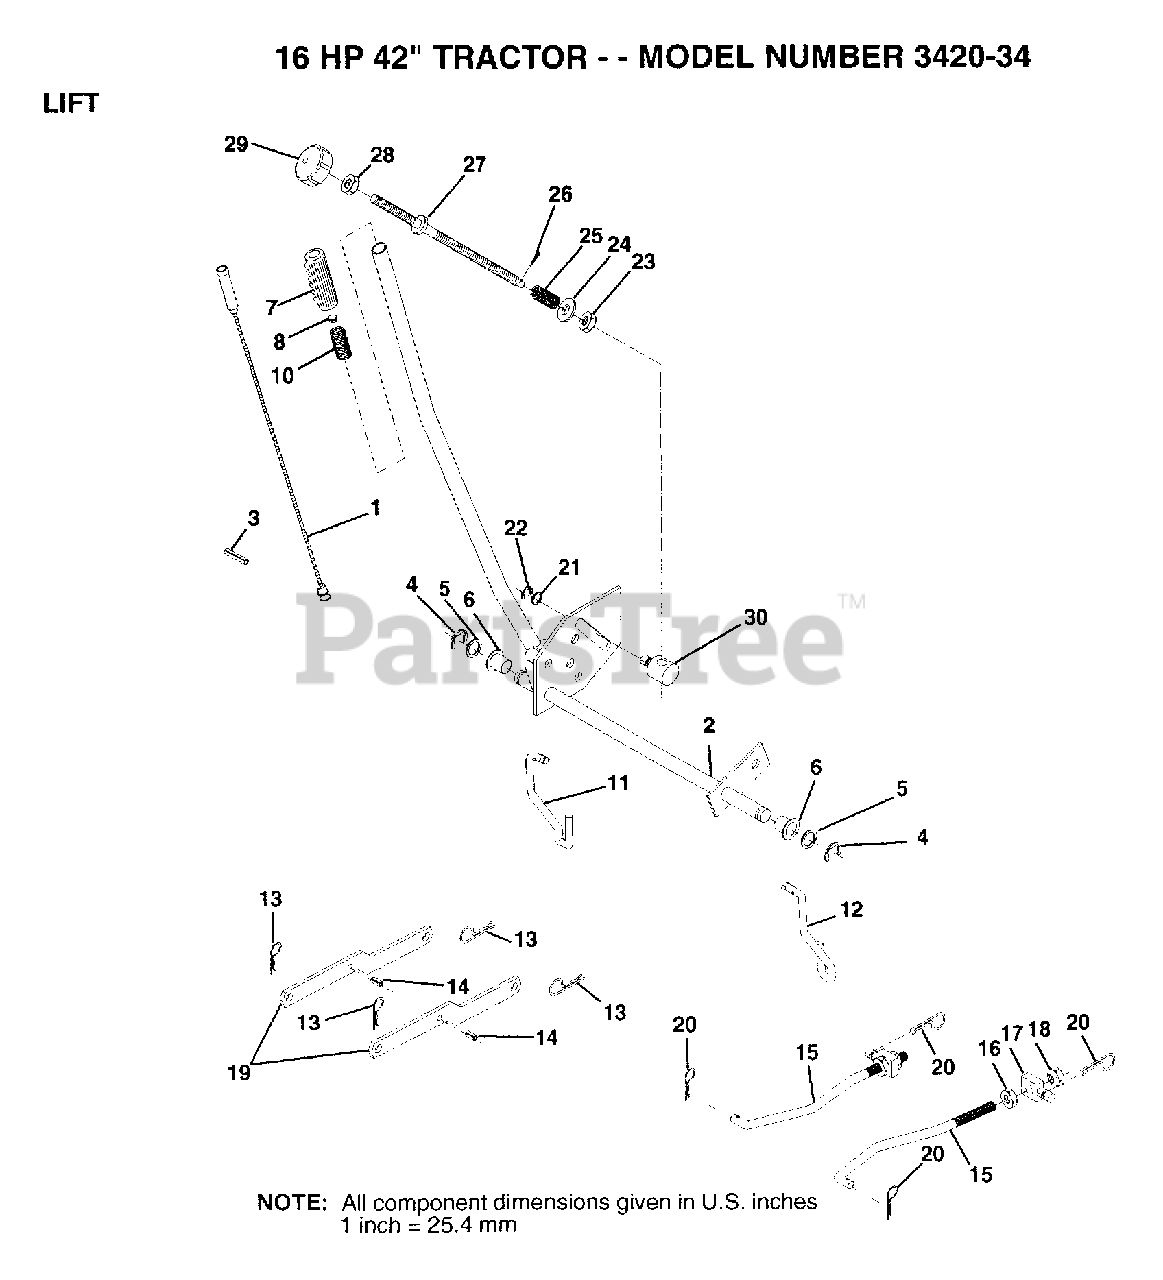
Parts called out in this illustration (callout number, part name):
1	WIRE ASM
2	SHAFT.ASM.LIFT LH
3	PIN GROOVE
5	WASHER
6	NYLON BEARING
7	GRIP
11	LINK LIFT LH
12	LIFT LINK RH
14	"PIN,SPRING"
15	LINK.FRONT
16	NUT
17	TRUNION
18	NUT.LK.W/WSH.1/2.
20	RETAINER.SPRING
21	WASHER
22	KLIP RING
23	NUT T
24	WASHER
25	SPRING T
27	ROD LIFT LT
28	NUT
29	KNOB INF 3/8-16
30	TRUNION LT
